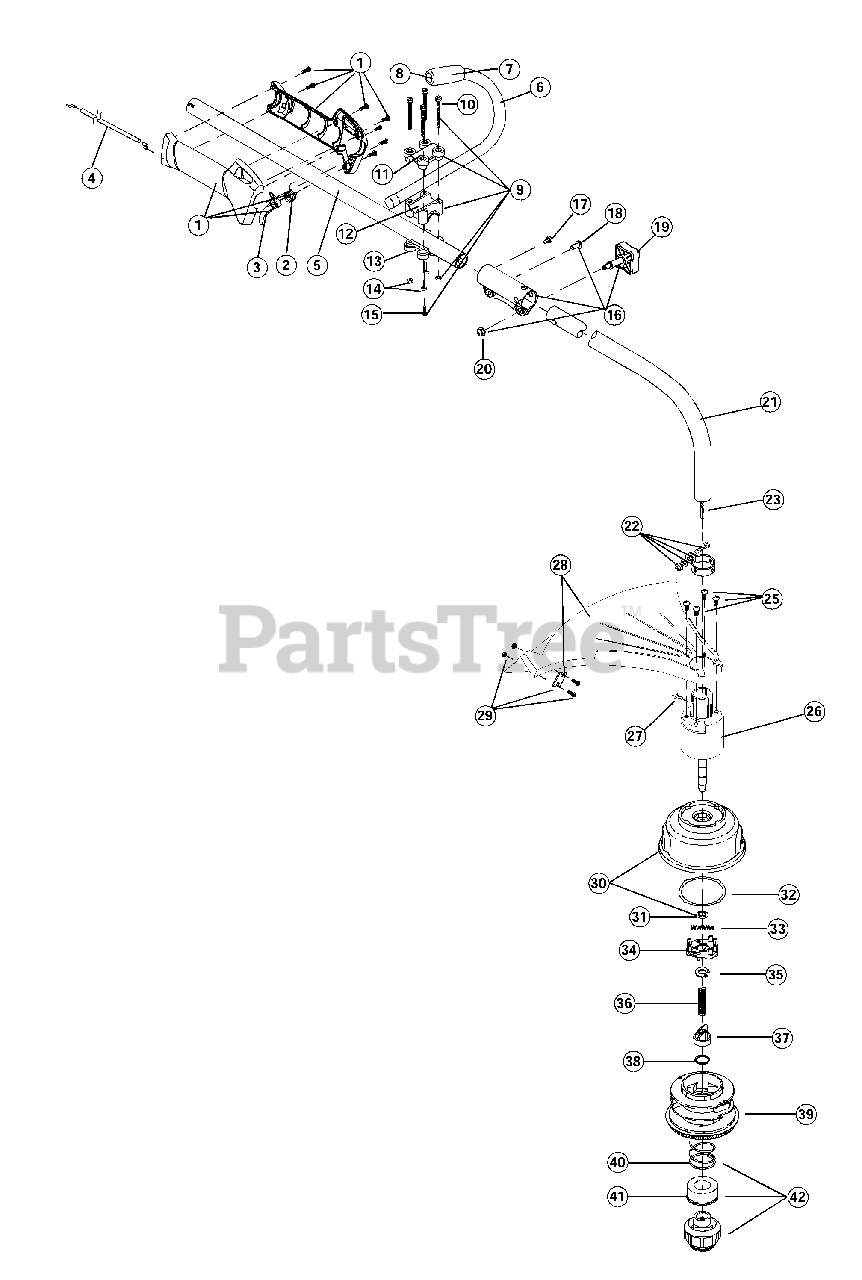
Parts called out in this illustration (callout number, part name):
1	Throttle Housing Assembly (Incl. 2 & 3)
2	Throttle Trigger Spring
3	Throttle Trigger
4	Throttle Cable Assembly
5	Upper Drive Shaft Housing Assembly
6	J-Handle Assembly (Incl. 7 & 8)
8	Tube Closure
9	Handle Bracket Assembly (Incl. 10-15)
11	Upper Handle Clamp
12	Middle Handle Clamp
13	Lower Handle Clamp
15	Anti-Rotation Screw
16	Click-Link Coupler (Incl. 17-20)
19	Adjustment Knob
20	Knob Retaining Nut
21	Lower Drive Shaft Housing Assembly
22	Lower Clamp Assembly
23	Lower Flexible Drive Shaft
25	Shield Mounting Screw
26	Bushing Housing Assembly
27	Anti-Rotation Screw
28	Shield and Blade Assembly (Incl. 29)
29	Blade Assembly
30	Outer Spool Assembly
31	Retainer
32	Thrust Washer
33	Small Spring
34	Slider
35	E-Clip
37	Plunger
39	Inner Reel
40	Large Spring
41	Foam Seal
42	Bump Head Knob Assembly (Incl. 40 & 41)
